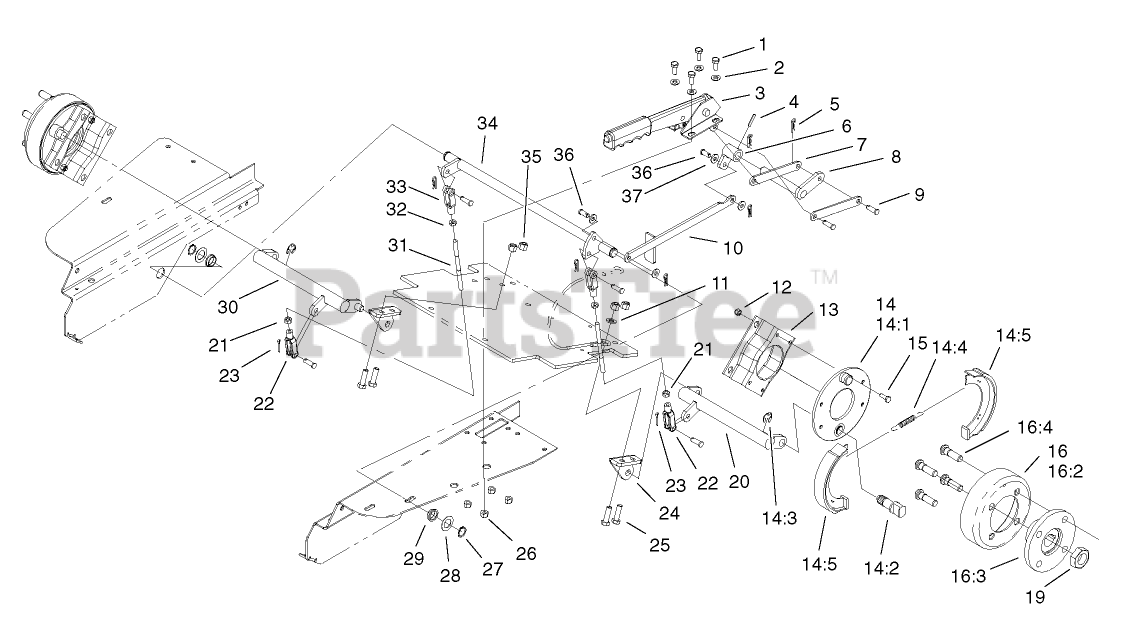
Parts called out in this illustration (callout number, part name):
1	SCREW-HH
2	WASHER-PLAIN
3	LEVER-BRAKE
4	PIN-SPIRAL
5	PIN-COTTER
6	BRAKE HUB ASM
7	LINK-BRAKE
8	TRANSFER SHAFT ASM
9	PIN-CLEVIS
10	CONNECTOR LINK ASM
11	WASHER-FLAT
12	NUT-LOCK, NI
13	BRACKET-BRAKE
14	BRAKE ASM
14:1	PLATE-BACKING
14:2	SHAFT-CAM, BRAKE
14:3	E-RING, BOWED
14:4	SPRING-RETURN
14:5	SHOE-BRAKE
15	SCREW-HH
16	BRAKE DRUM ASM
16:2	DRUM-BRAKE
16:3	HUB-WHEEL
16:4	STUD-DRIVE
19	NUT-LOCK
20	LH BRAKE LEVER ASM
21	NUT-JAM
22	CLEVIS-ADJUSTABLE
23	PIN-COTTER
24	MOUNT-LEVER, BRAKE, RH
25	SCREW-HH
26	NUT-LOCK, NI
27	Ring-Snap
28	WASHER-FLAT
29	BUSHING
30	RH BRAKE LEVER ASM
31	ROD-BRAKE
32	NUT-JAM
33	YOKE
34	TORSION SHAFT ASM
35	NUT-LOCK, NI
36	PIN-CLEVIS
37	WASHER-FLAT
